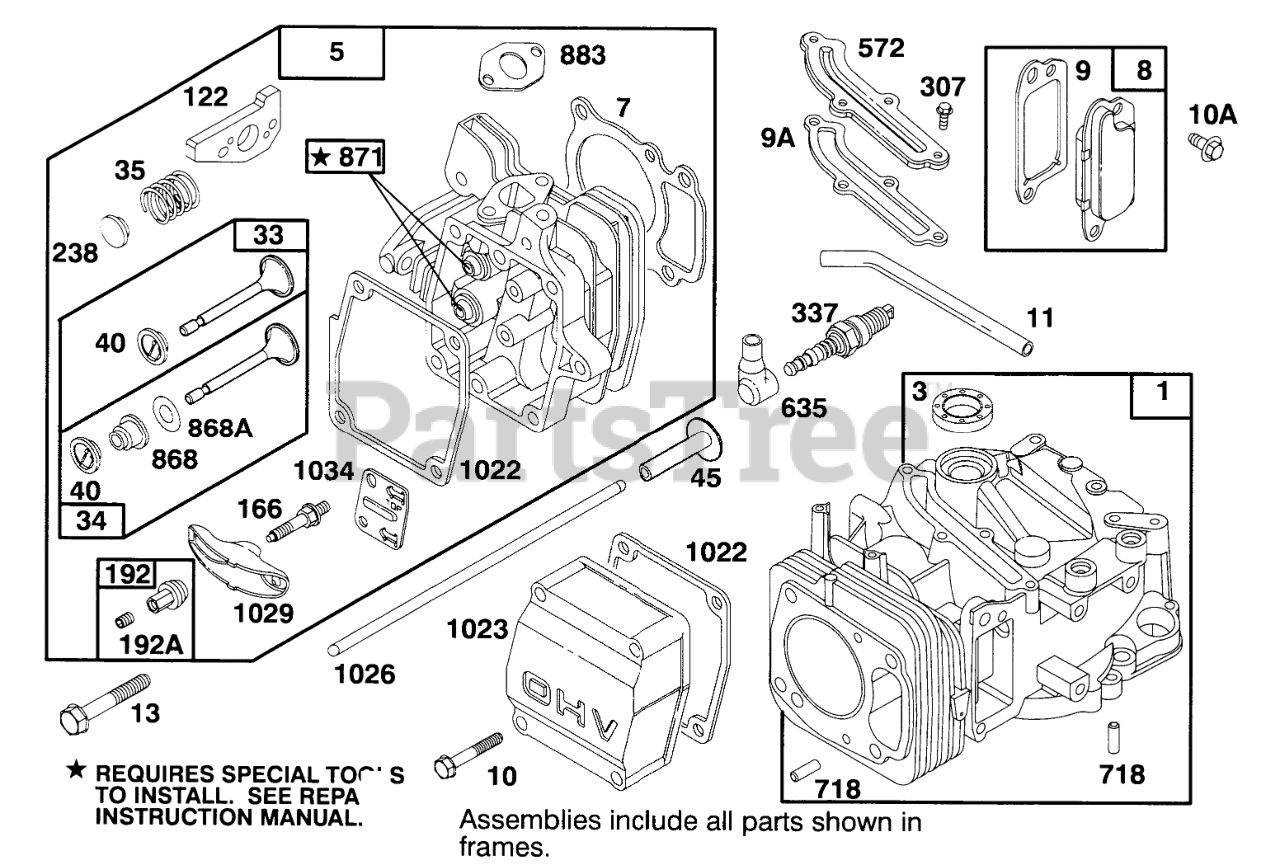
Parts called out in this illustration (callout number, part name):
1	CYLINDER ASSEMBLY
3	SEAL - OIL
5	CYLINDER HEAD
7	CYLINDER HEAD GASKET
8	Breather Assy
9	BREATHER GASKET
9A	GASKET-BREATHER
10	HEX HEAD SCREW
10A	HEX HEAD SCREW
11	TUBE - BREATHER
13	CYLINDER HEAD SCREW
33	EXHAUST VALVE
34	INTAKE VALVE
35	VALVE SPRING
40	SPRING RETAINER
45	VALVE TAPPET
122	ADAPTER ASSEMBLY
166	ROCKER ARM STUD
192	NUT - HEX SPECIAL
192A	SCREW SET
238	VALVE CAP
307	SCREW - SEM
337	PLUG-SPARK
572	BAFFLE - CYCLINDER
635	SPARK PLUG ELBOW
718	DOWEL - SLEEVE
868	SealAssy-Valve
868A	Seal-Valve
871	Bushing-Guide
883	EXHAUST GASKET
1022	ROCKER COVER GASKET
1023	COVER - VALVE
1026	PUSH ROD
1029	ROCKER ARM
1034	PUSH ROD GUIDE
